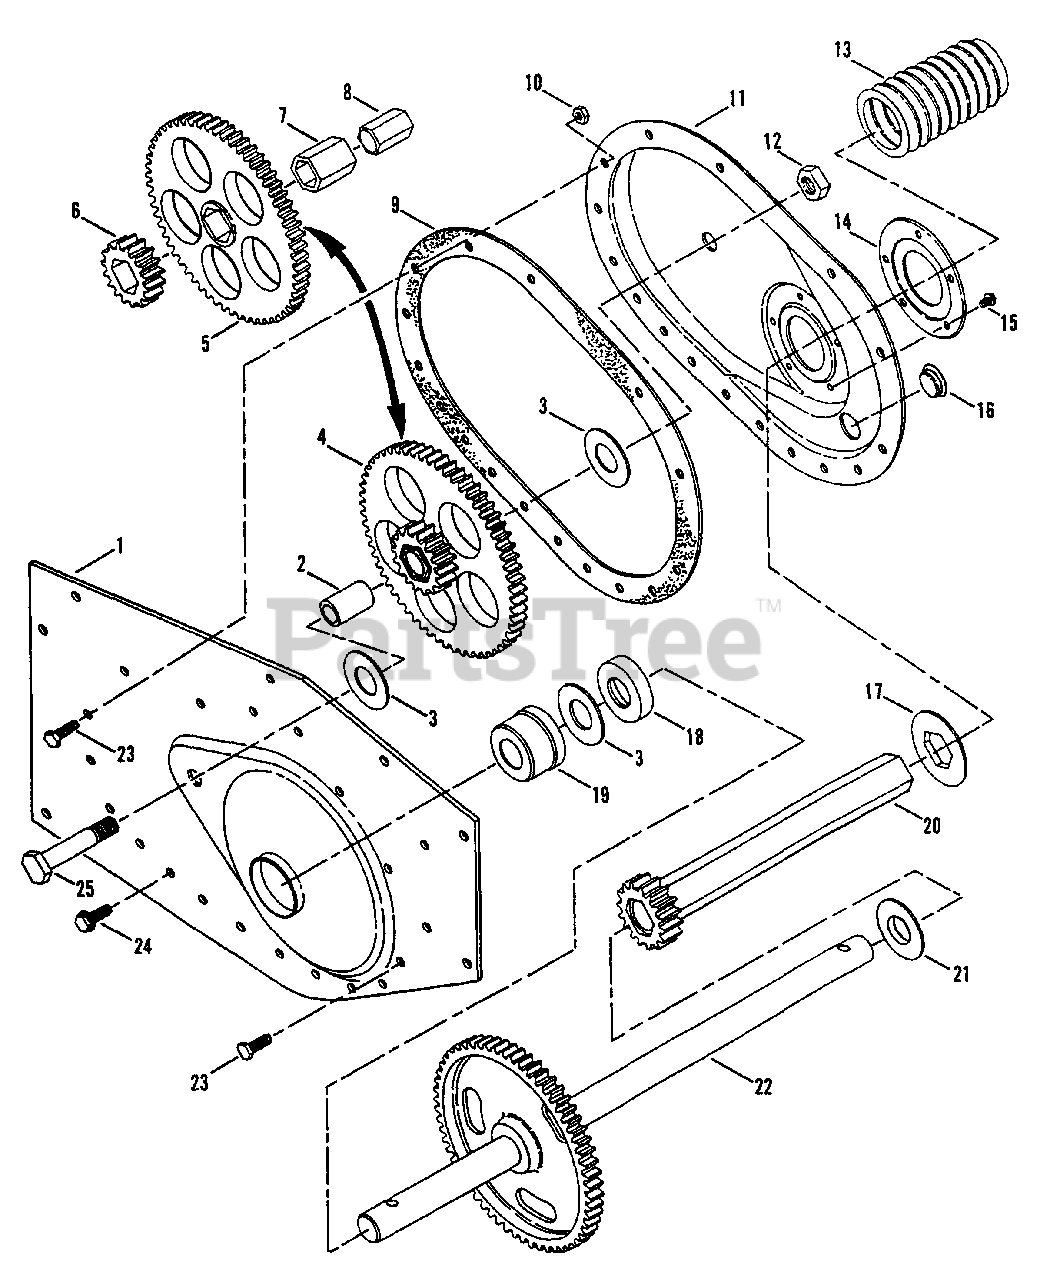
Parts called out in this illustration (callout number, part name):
1	FRAME, Left Side
2	SHAFT
3	WASHER, Thrust
4	ASSEMBLY, Cluster Gear
5	GEAR, 63 Tooth
6	GEAR, 16 Tooth
7	TUBE, Hex
8	BEARING, Hex
9	(NLA) GASKET
10	NUT, 1/4-28 Hex Top-Lock
12	NUT, 1/2-20 Hex Center-Lock
13	SEAL, Short
14	(NLA) RETAINER, Boot
15	SCREW, #10-32 x 1/4" Self-Tapping
16	PLUG, 3/4"
17	WASHER, Plastic
19	BEARING, Axle .76" ID x 1.626"/1.75" OD x 1.06" Long
20	ASSEMBLY, Tube Drive
21	WASHER, Thrust
22	STRUCTURE, Axle
23	SCREW, 1/4-28 x 1/2" Hex Head Cap, Grade 5
24	SCREW, 1/4-20 x 1/2" Self-Tapping
25	(NLA) SCREW, 1/2-20 x 1 7/8" Hex Head Cap
